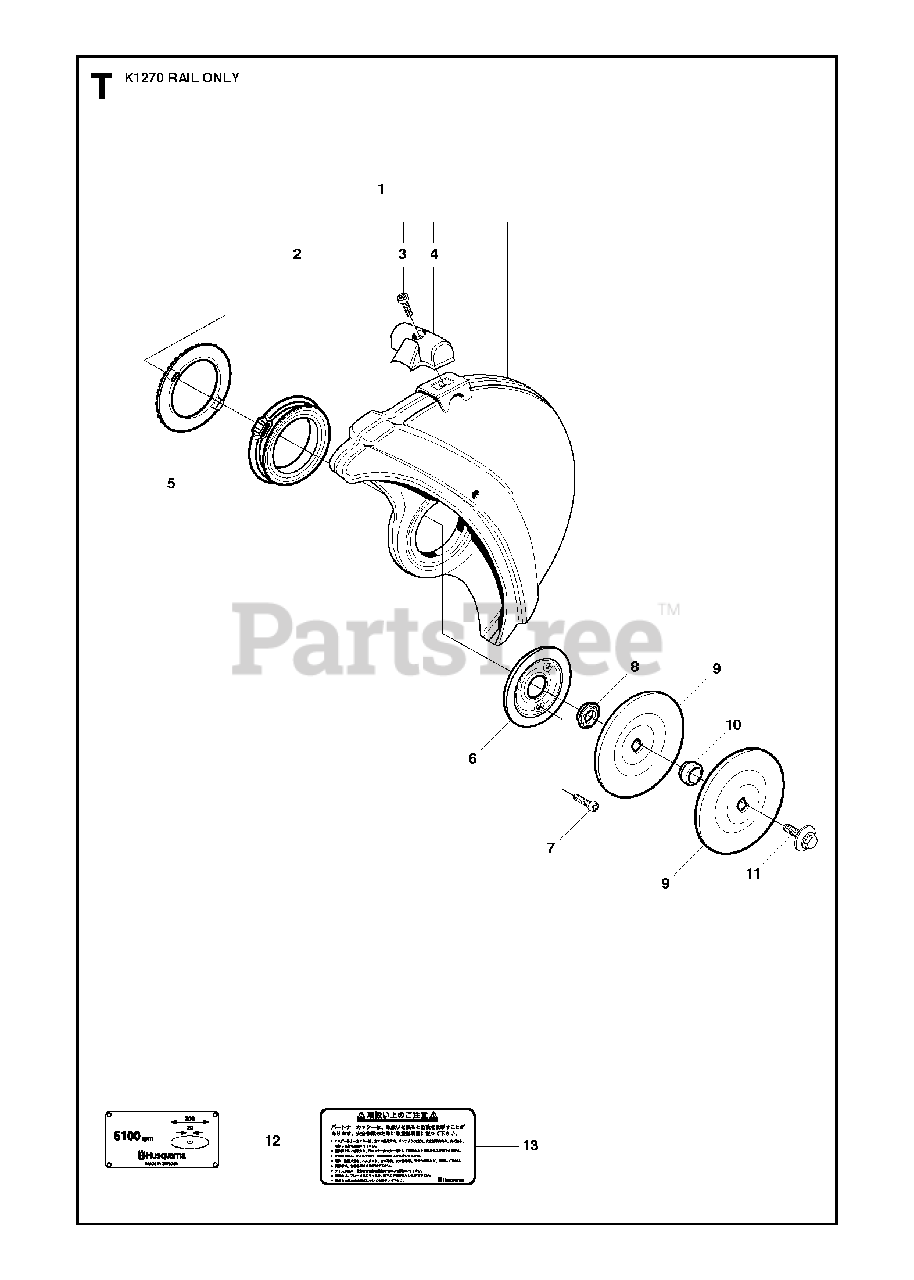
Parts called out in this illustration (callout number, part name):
1	BLADE GUARD"14"" Rail"
1	BLADE GUARD"16"" Rail"
3	SCREW ITXSCM
7	SCREW ITXSCM
8	SUPPORT FLANGE
9	FLANGE WASHERDiam 119
10	KITDiam 22,2
10	BUSHINGDIAM 30,5
12	LABEL"14"" Diam 20 mm"
12	LABEL"16"" Diam 20 mm"
13	DECAL"14"""
